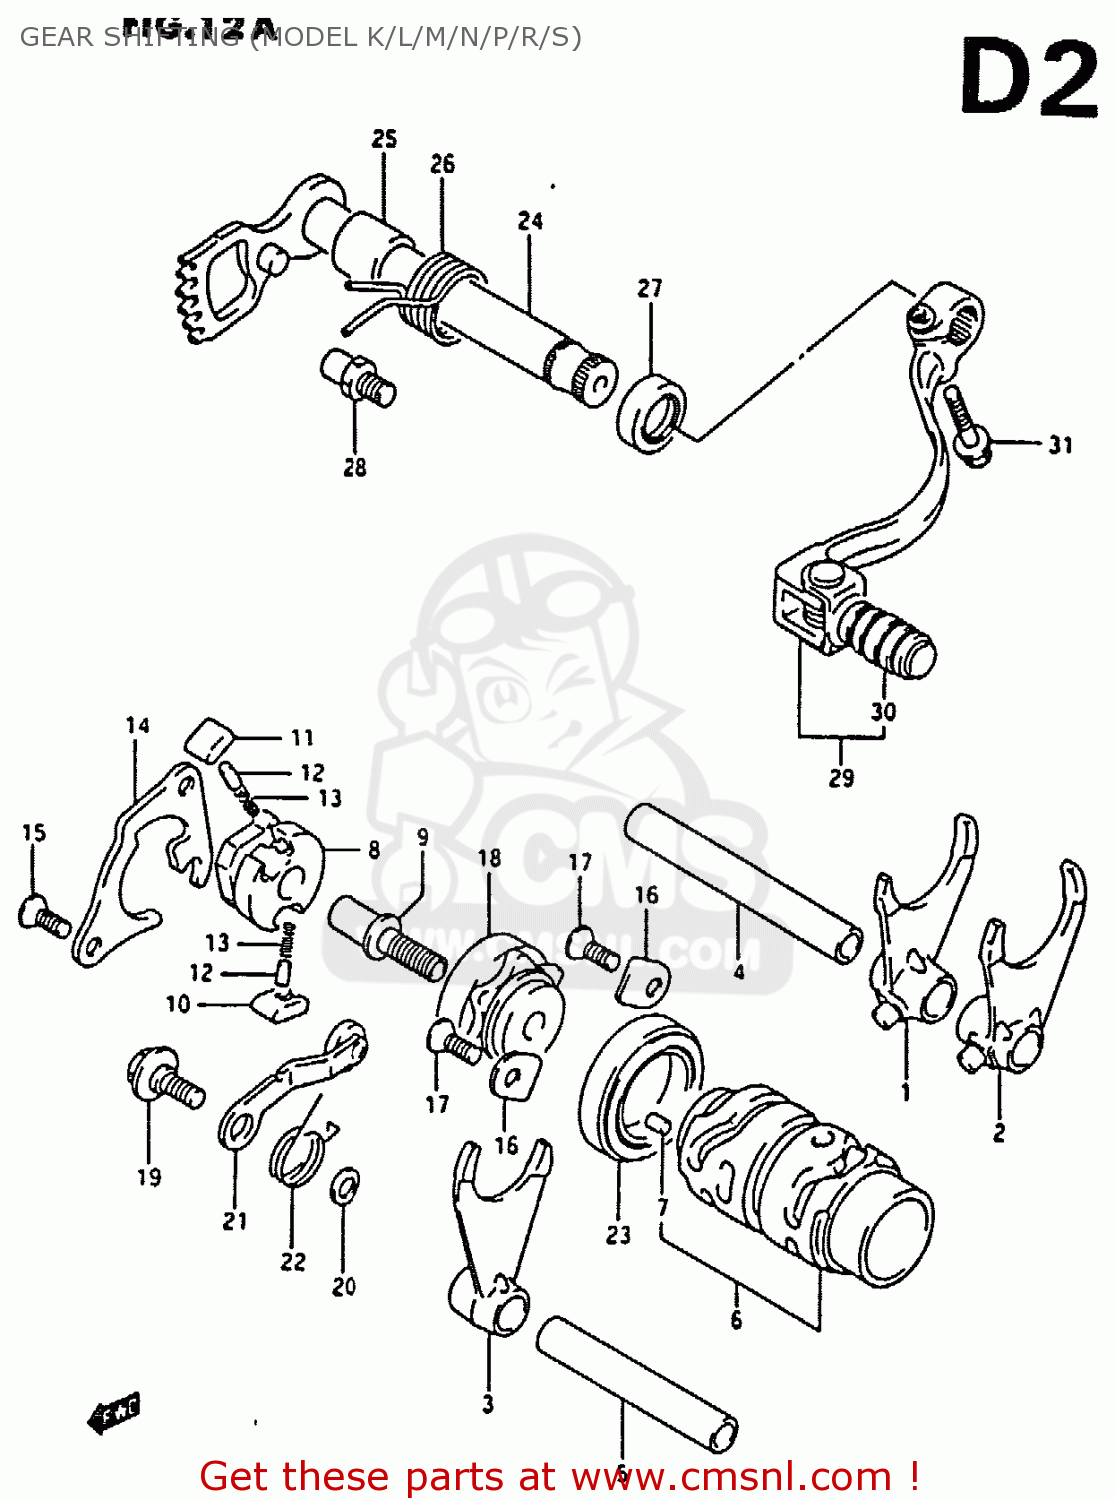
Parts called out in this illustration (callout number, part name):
1	FORK,GEAR SHIFT NO.1
2	FORK,GEAR SHIFT NO.2
3	FORK,GEAR SHIFT NO.3
4	SHAFT,GEAR SHIFT FORK
5	SHAFT,GEAR SHIFT FORK
6	CAM,GEAR SHIFT
7	PIN
8	GEAR,GEARSHIFT CAM DRIVE
9	PIN, SHIFT CAM DRIVEN GEAR
10	PAWL,GEAR SHIFT NO.1
11	PAWL,GEAR SHIFT NO.2
12	PIN(5X8)
13	SPRING
14	LIFTER,GEAR SHIFT POLE
15	SCREW
16	RETAINER,COUNTER BEARING,R
17	SCREW
18	PLATE,GEAR SHIFT CAM STOPPER
19	BOLT(6X14.3)
20	WASHER
21	STOPPER,SHIFT CAM
22	SPRING
23	BEARING
24	SHAFT,GEAR SHIFT
25	SPACER(14X20X17.5)
26	SPRING
27	SEAL,OIL(14X22X6)
28	STOPPER,GEAR SHIFT CAM
29	LEVER ASSEMBLY,GEAR SHIFTING
30	RUBBER,GEAR SHIFT PEDAL
31	BOLT,G/S SWITC
